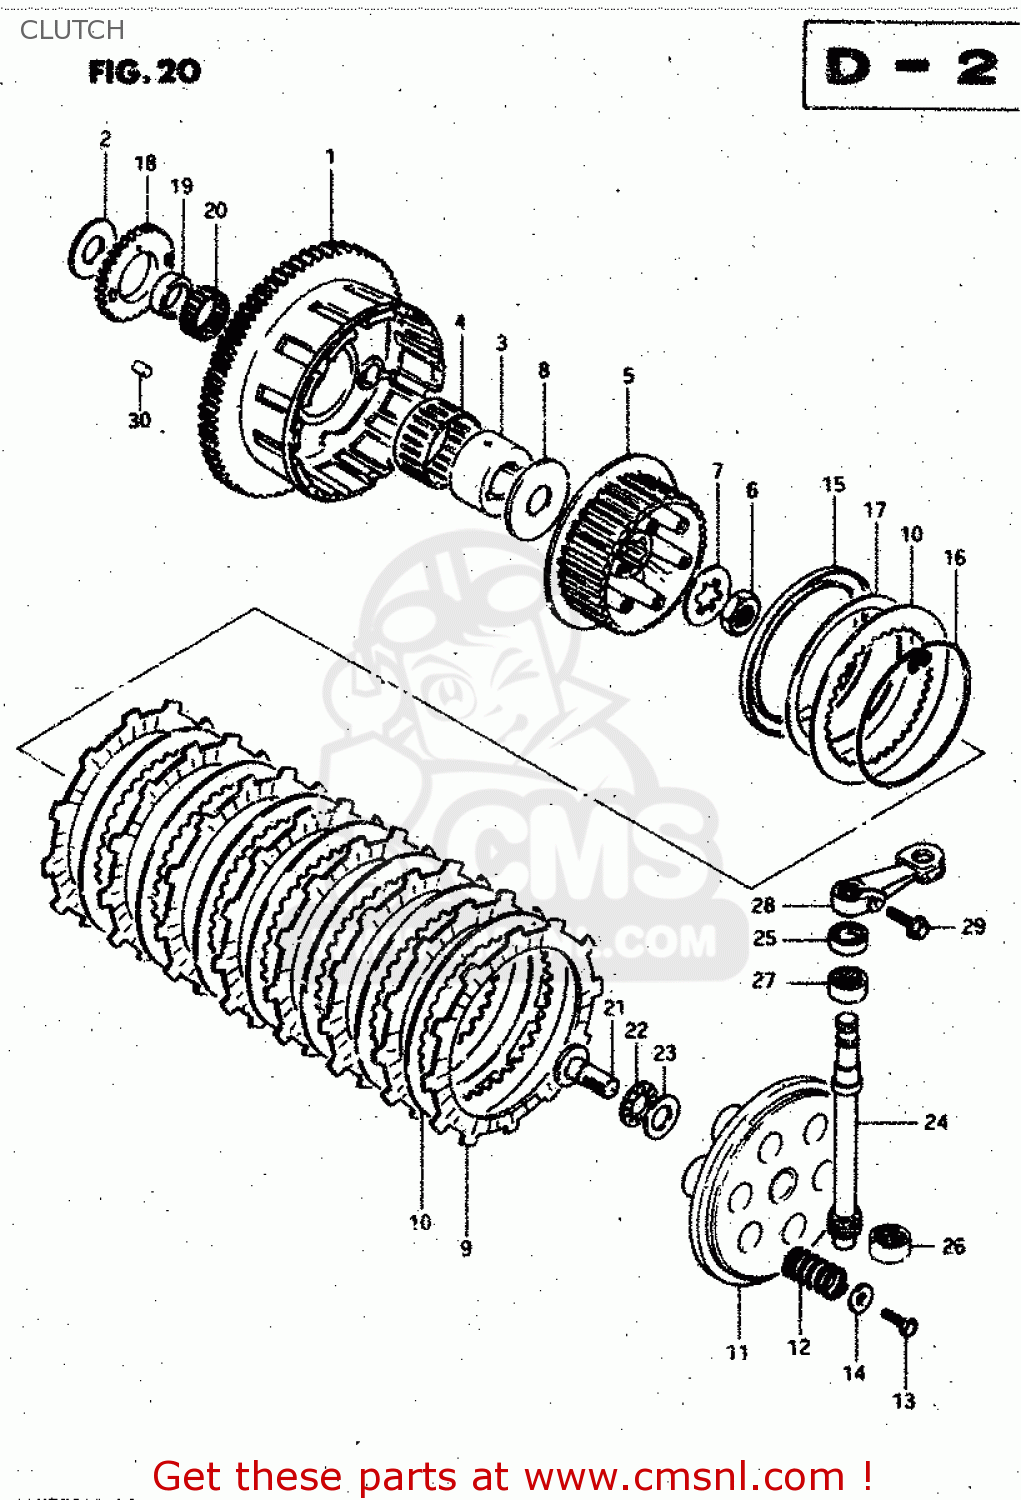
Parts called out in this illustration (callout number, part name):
1	GEAR ASSEMBLY,PRIMARY DRIVE
2	WASHER
3	SPACER
4	BEARING(51X56X28)
5	HUB,CLUTCH SLEEVE
6	NUT
7	WASHER,LOCK
8	WASHER(25X66X3.5)
9	PLATE,CLUTCH DRIVE (MCA)
10	PLATE,CLUTCH DRIVEN(T:2.0) (NAS)
11	DISC,CLUTCH PRESSURE
12	SPRING
13	BOLT, UPPER
14	WASHER
15	SEAT,WAVE WASHER
16	RING,STOPPER
17	WASHER
18	GEAR,ENG OIL PUMP DRIVE(NT:38)
19	SPACER,OIL PUMP DRIVE GEAR
20	BEARING(36X40X10)
21	RACK,CLUTCH RELEASE
22	BEARING(15X28X2)
23	WASHER
24	PINION,CLUTCH RELEASE
25	OIL SEAL
26	BEARING(12X19X12)
27	BEARING(15X22X12)
28	ARM,CLUTCH RELEASE
29	BOLT (6X20)
30	CUSHION,PRIMARY DRIVEN GEAR
